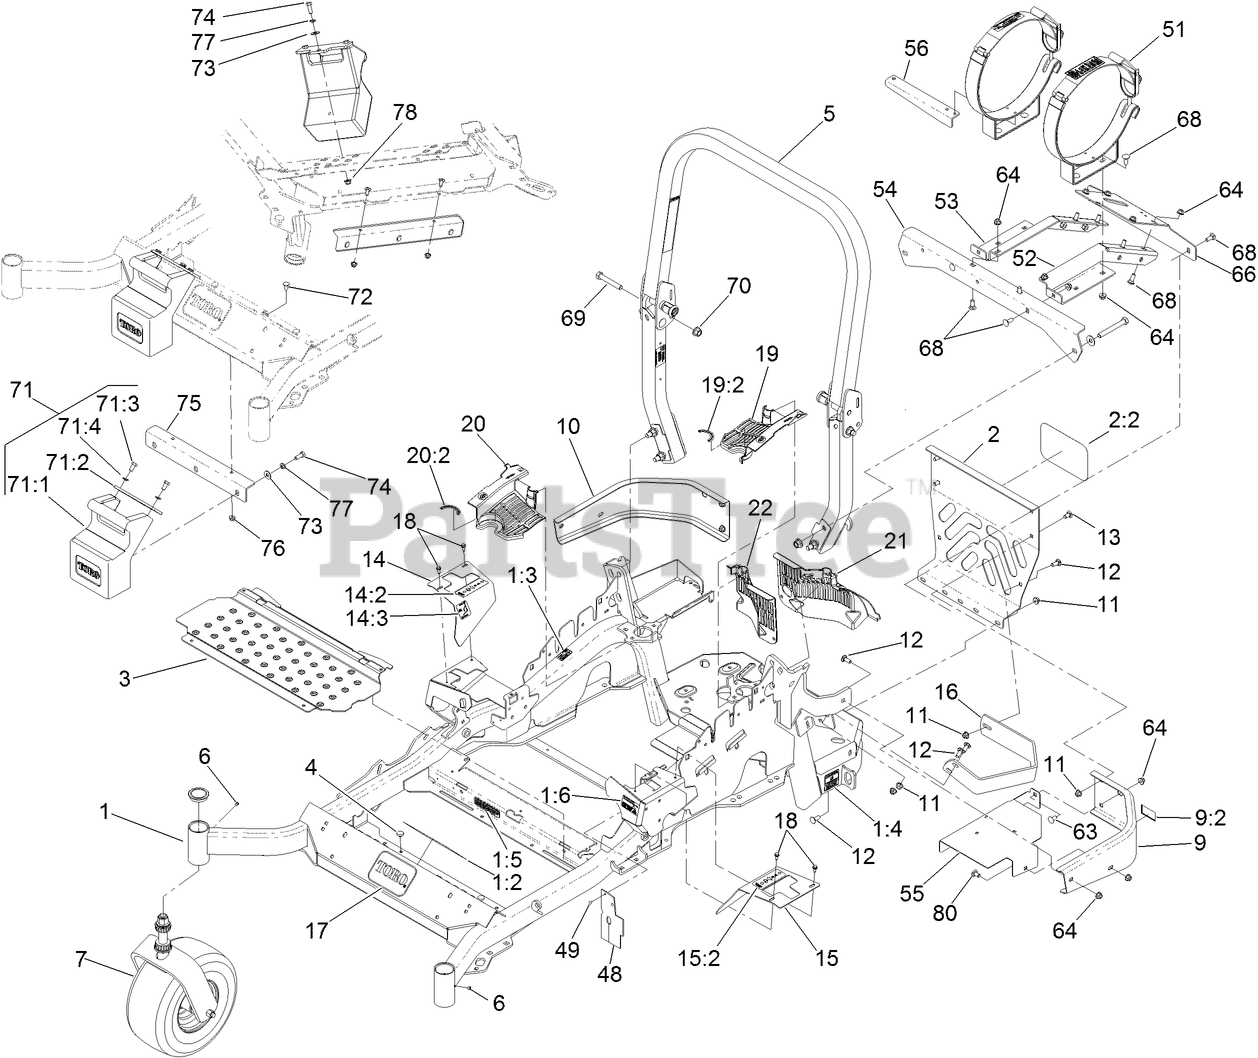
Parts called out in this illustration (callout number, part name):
1	MAIN FRAME ASM
1:2	DECAL-SLOPE
1:3	DECAL-CAUTION
1:4	DECAL-BELT DRIVE
1:5	DECAL-ARRESTER, SPARK
1:6	DECAL-FUEL FILL
2	REAR GUARD ASM
2:2	DECAL
3	FLOORPAN
4	BUMPER
5	ROPS ASM
7	Caster Wheel ASM
9	LH BUMPER ASM
9:2	DECAL-CAUTION
10	BUMPER-RH
11	NUT-HF, NI
12	SCREW-CARR
13	SCREW-CARR
14	RH MOTION CONTROL COVER ASM
14:2	DECAL-MOTION CONTROL
14:3	DECAL-PARK BRAKE
15	LH MOTION CONTROL COVER ASM
15:2	DECAL-MOTION CONTROL
16	GUARD-MUFFLER
17	DECAL
18	SCREW-HWH
19	LH HYDRO GUARD ASM
19:2	DECAL-HYDRO OIL
20	RH HYDRO GUARD ASM
20:2	DECAL-HYDRO OIL
21	GUARD-HYDRO, REAR (LH)
22	GUARD-HYDRO, REAR (RH)
48	DEFLECTOR-AIR FLOW
49	RIVET-POP
51	TANK BRACKET ASM (SET)
52	LH LPG FRAME ASM
53	RH LPG FRAME ASM
54	SUPPORT-LPG FRAME, FRONT
55	PANEL-LPG, AC
56	PLATE-INDEX, LPG TANK
63	SCREW-HH
64	NUT-HF, NI
66	SUPPORT-REAR FRAME, LPG
68	BOLT-CARR
69	SCREW-HH
70	NUT-LOCK
71	WEIGHT ASM
71:1	WEIGHT-43 LB
71:2	TAB-SUPPORT, WEIGHT
71:3	SCREW-HH
71:4	WASHER-LOCK
72	SCREW-CARR
73	WASHER-FLAT
74	SCREW-HH
75	BRACKET-MOUNT, WEIGHT
76	NUT-HF, NI
77	WASHER-LOCK
78	NUT-HF, NI
80	SCREW-CARR
